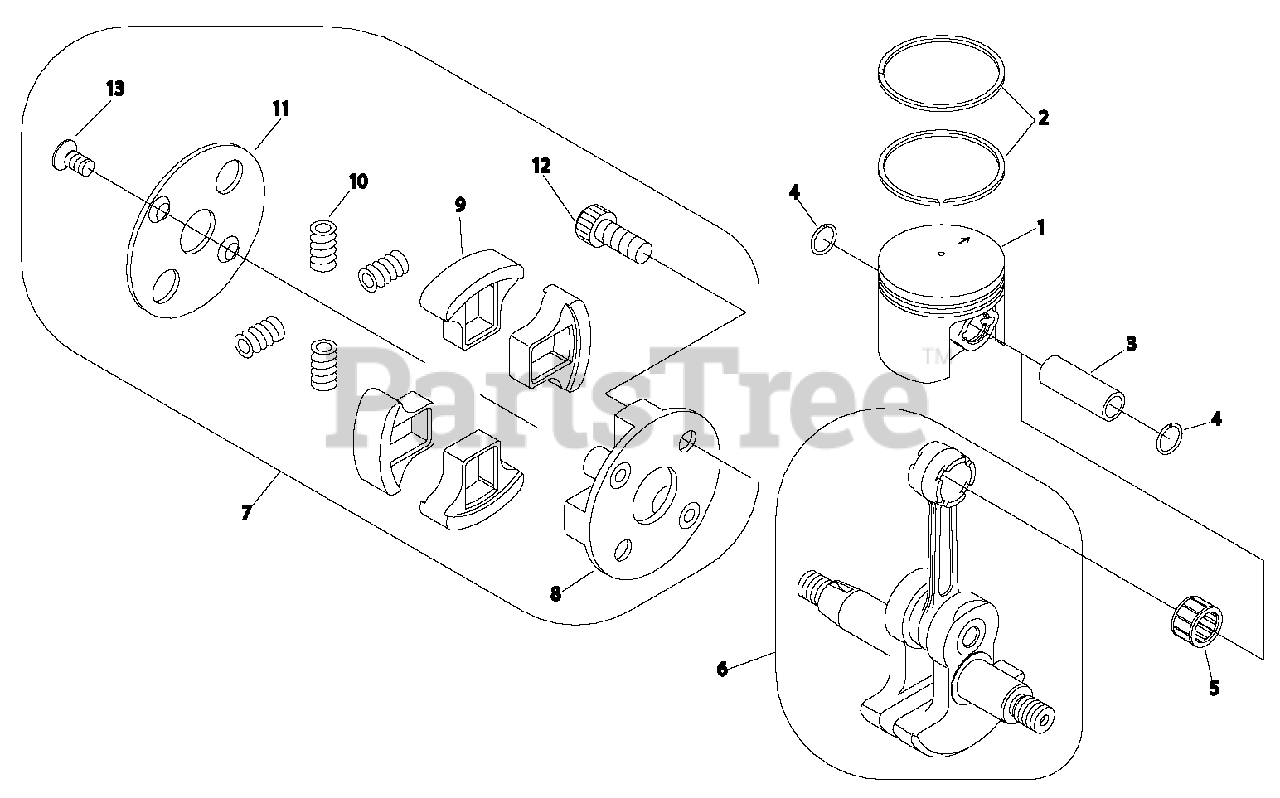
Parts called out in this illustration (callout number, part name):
1	PISTON
2	PISTON RING SET
3	PIN, PISTON
4	RING, RETAINING
5	BEARING, NEEDLE - C82
6	CRANKSHAFT ASSY
7	CLUTCH ASSY
8	HUB, CLUTCH
9	SHOE, CLUTCH
10	SPRING, CLUTCH
11	PLATE, CLUTCH
12	BOLT, CLUTCH
13	SCREW
